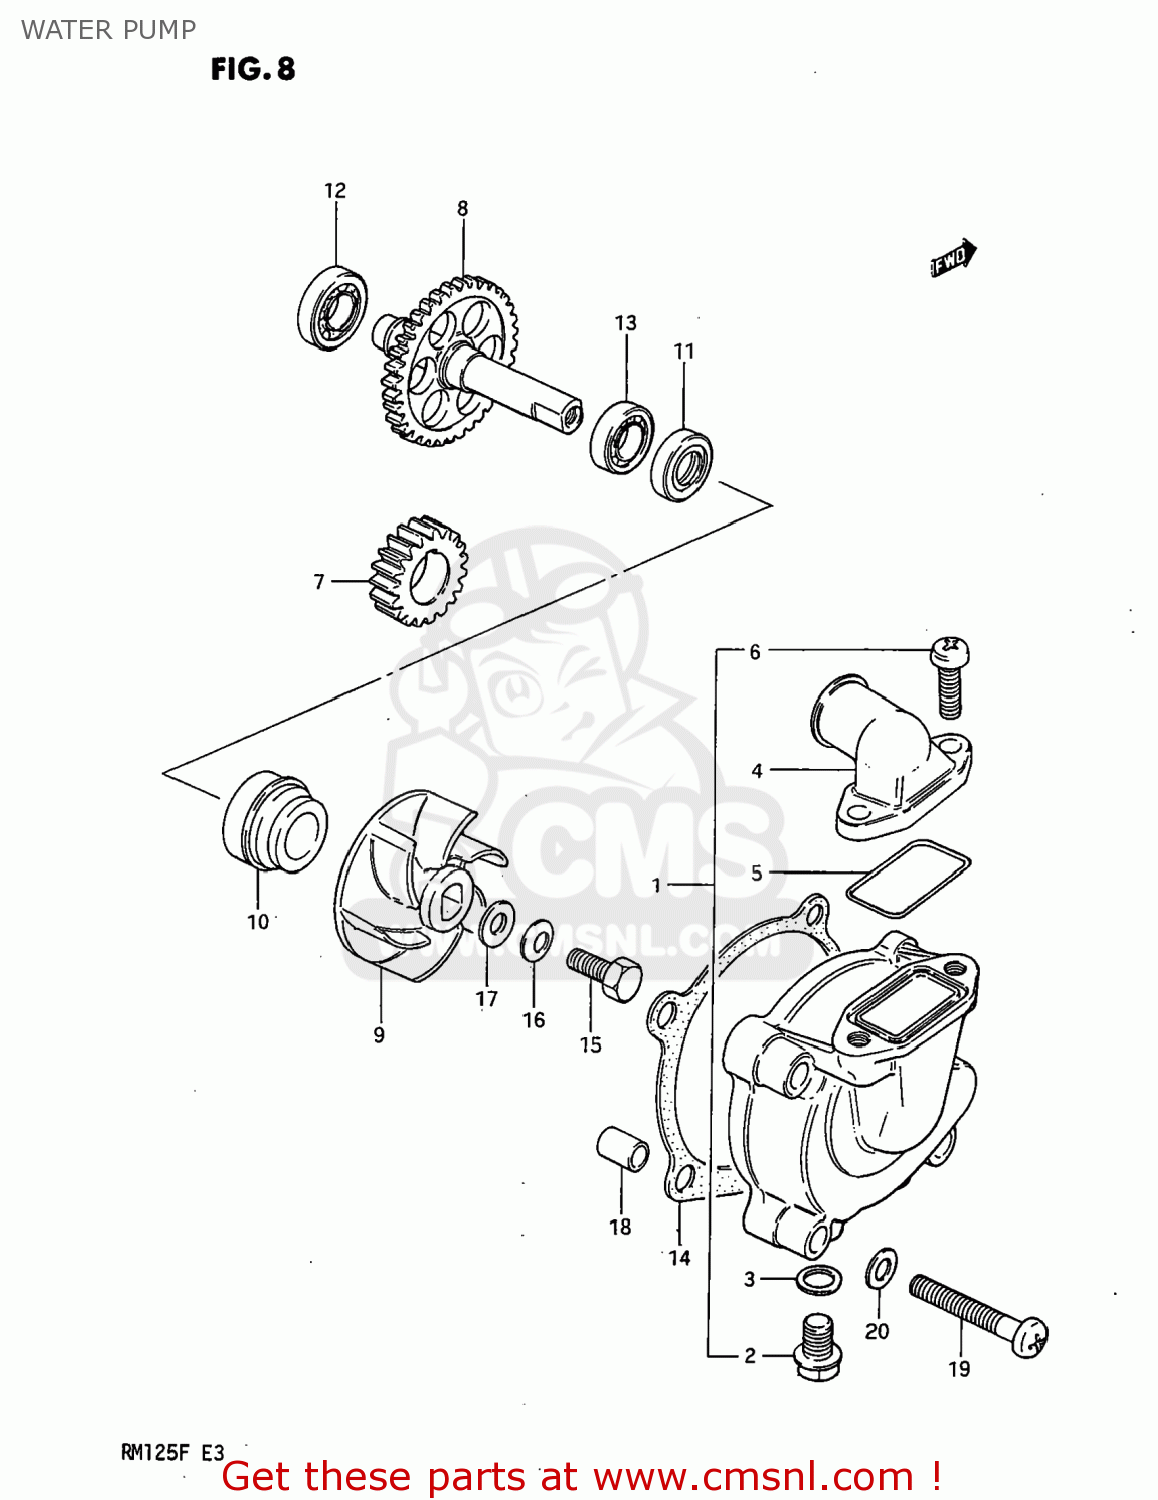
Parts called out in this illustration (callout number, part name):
1	CASE,WATER PUMP
2	BOLT,DRAIN
3	GASKET,DRAIN (NAS)
4	CONNECTOR
5	O RING,WATER PUMP CONNECTOR
6	SCREW
7	GEAR,WATER PUMP DRIVE
8	GEAR,WATER PUMP DRIVEN(NT:36)
9	IMPELLER,WATER PUMP
10	SEAL,WATER PUMP SHAFT
11	SEAL,OIL(10X21X5)
12	BEARING(10X22X6)
13	BEARING
14	GASKET,WATER PUMP CASE (MCA)
15	BOLT(6X13)
16	WASHER
17	GASKET (NAS)
18	PIN
19	SCREW
20	WASHER
